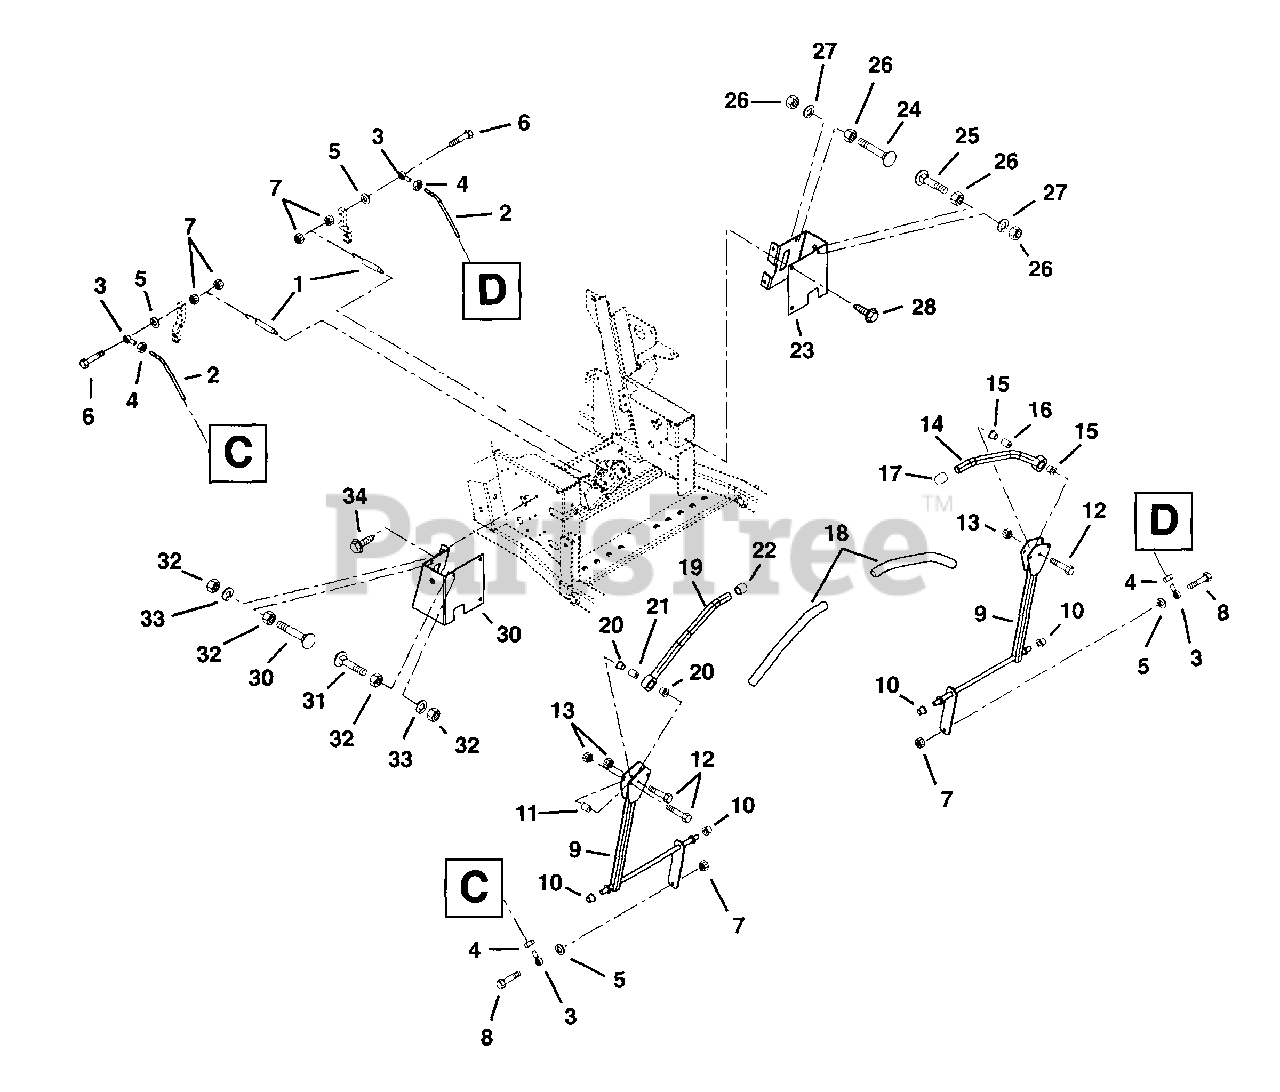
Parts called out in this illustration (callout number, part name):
1	Spring-Tension .062 x .56 x 8.0
2	Rod-Steering Adjustment
3	Rod End 5/16 Right-Hand-Female
4	Nut-Jam .31-24
5	Washer-Locking .31 x .078
6	Bolt-Hex .31-18 x 1.75 Grade 5
7	Nut-Locking-Center .31-18
8	Bolt-Hex .31-18 x 1.50 Grade 5
9	Rod-Steering
10	Bushing-Flange .515 x .750 x .745 x 1.00
11	Eccentric
12	Bolt-Hex .31-18 x 1.75 Grade 5
13	Nut-Locking-Center .31-18
14	Handle Weldment Left-Hand
15	Bushing-Flange-Nylon .762 x 1.48 x .44
17	End Cap-Steering Lever Tube
18	Grip-Handlebar
19	Handle Weldment Right-Hand
20	Bushing-Flange-Nylon .762 x 1.48 x .44
22	End Cap-Steering Lever Tube
23	Mount-Steering Rod-Left Hand
24	Bolt-Round Head Square Neck .38-16 x 2.00
25	Bolt-Round Head Square Neck .38-16 x 1.50
26	Nut-Hex .38-16
27	Washer-Locking .38 x .094
28	Screw-Tapping .38-16 x .75 Hex Washer Head
29	Mount-Steering Rod-Right Hand
30	Bolt-Round Head Square Neck .38-16 x 2.00
31	Bolt-Round Head Square Neck .38-16 x 1.50
32	Nut-Hex .38-16
33	Washer-Locking .38 x .094
34	Screw-Tapping .38-16 x .75 Hex Washer Head
